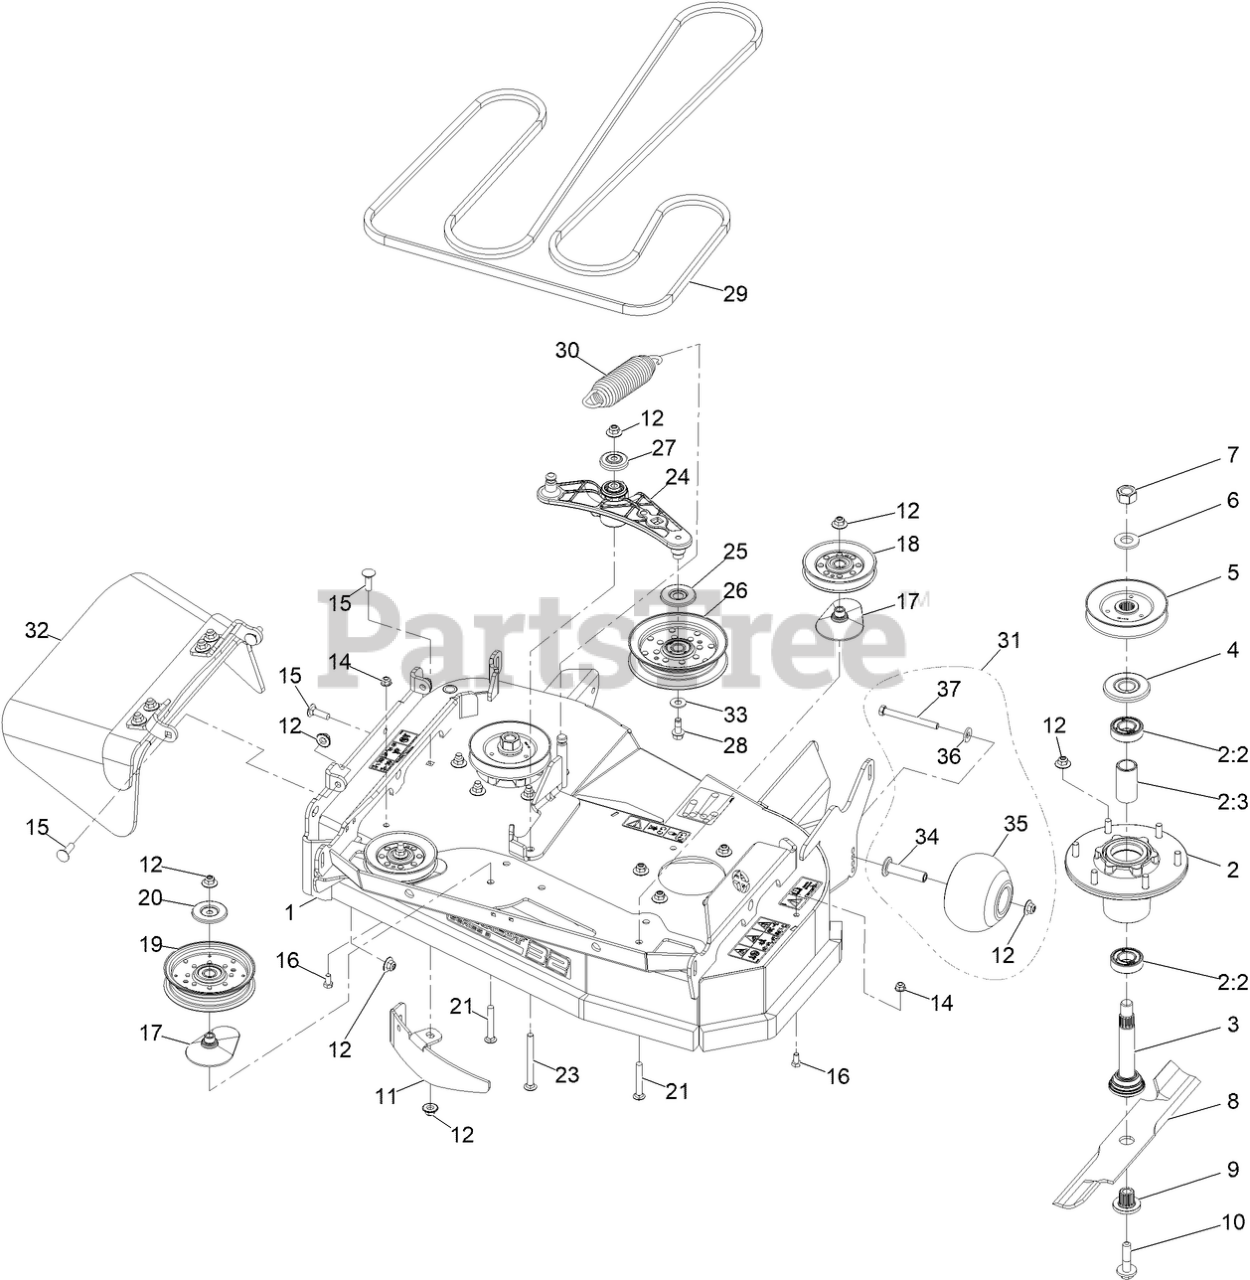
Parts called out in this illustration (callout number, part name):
1	ASM-DECK DECALS 32
2	ASM-CUTTER HSG WITH BEARINGS
2:2	BEARING-BALL
2:3	SPACER-BEARING
3	ASM-SPINDLE AND SEAL
4	GUARD,BEARING TOP .989
5	SHEAVE-BLADE DRIVE
7	NUT-HEX
9	BUSHING,SPLINED
10	SCREW,SEMS 1/2-20 X 2.19
11	BAFFLE, DOGLEG
12	Nut-Nyloc 3/8-16 Flg
14	NUT-HF, NI
15	BOLT-CARR
16	SCREW-HH
17	SPACER-PULLEY
18	Idler - V 4.13 Eod-A
19	PULLEY-IDLER, FLAT
20	SHIELD-DUST
21	SCREW-CARR
23	SCREW-CARR
24	ASM.-ARM, IDLER
25	SHIELD-GUARD, DUST
26	IDLER-PULLEY, FLAT
27	GUARD-TOP
28	SCREW-HFH
30	SPRING-EXTENSION
31	KIT, ANTI-SCALP ROLLER
32	RUBBER DEFLECTOR ASM
33	WASHER-FLAT
34	AXLE, ROLLER
35	ROLLER-SCALP, ANTI
36	WASHER-BELLEVILLE
37	SCREW-HH 3/8-16 X 3 3/4 GR 8
